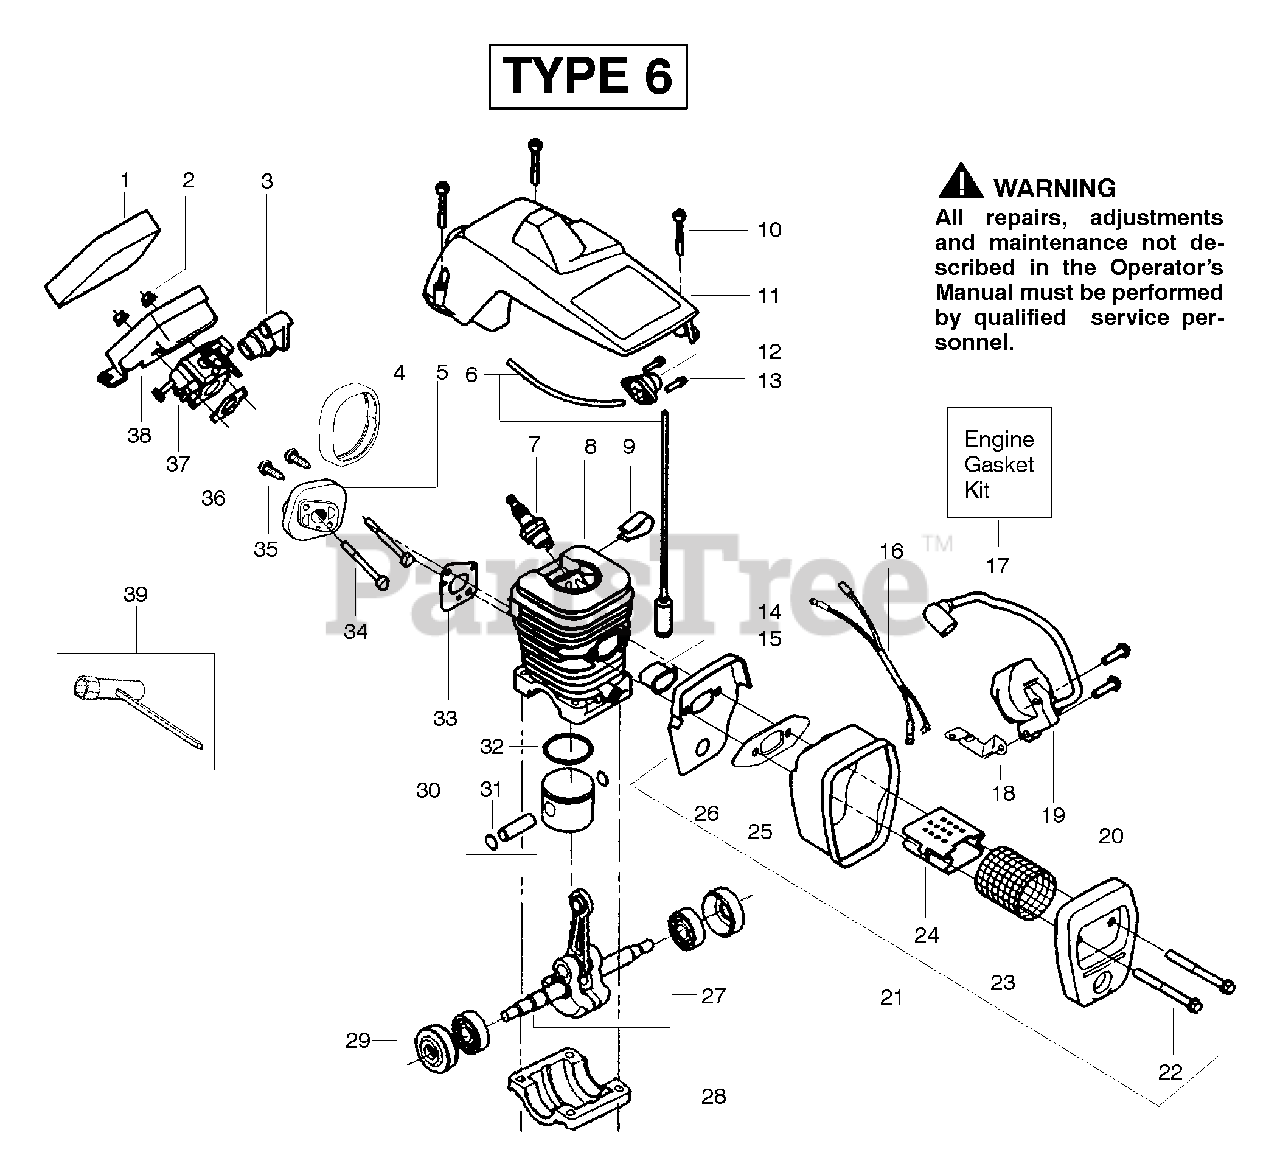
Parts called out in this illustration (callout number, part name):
1	Foam-Air Filter
3	Grommet-Carb Adjust
4	Seal-Carb Adapter
5	Adapter-Carb.
6	Kit-Fuel Line (Small)
7	Spark Plug (RCJ-7Y)
8	Kit-Cylinder
9	Clip-High Tension Lead
11	Shield-Cylinder
12	Assy-Air Purge
14	Assy-Fuel Pick-up
15	Insulator-Heat
16	Assy.-Wire Harness
17	Kit-Engine Gasket
18	Strap-Ground
19	Module-Ignition
21	Assy-Muffler
23	Screen-Spark
24	Diffuser-Muffler
25	Gasket-Muffler (kit)
26	Backplate-Muffler
27	Assy.-Crankshaft
28	Cap-Crankcase
29	Assy.-Seal & Bearing
30	Kit-Piston
31	Retainer-Piston Pin
32	Ring-Piston
33	Gasket-Adapter (kit)
36	Gasket-Carb. (kit)
37	Kit-Carburetor (WT-624)
38	Housing-Air Filter
39	Wrench-Bar
